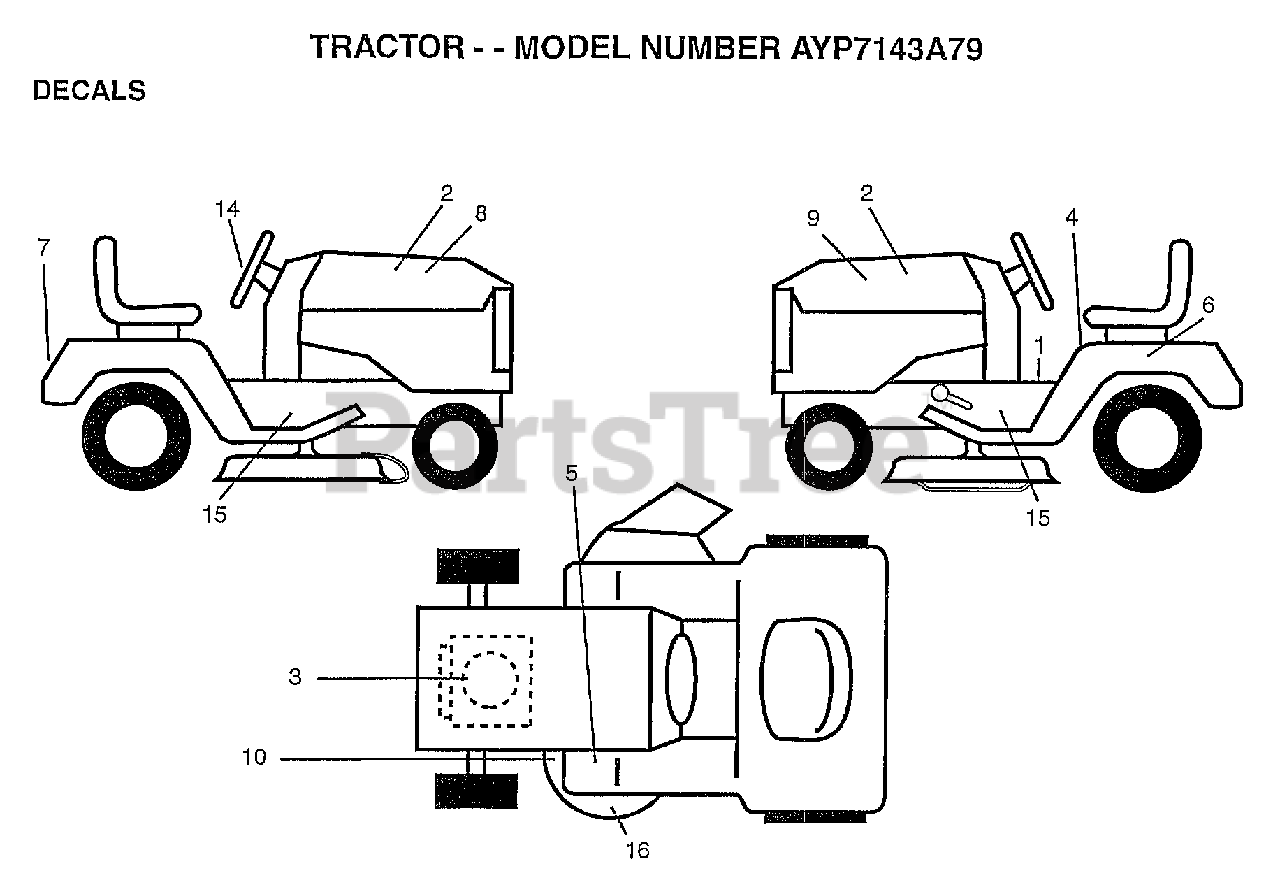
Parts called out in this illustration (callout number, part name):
1	"DECAL DASH,OPER."
2	DECAL.INS.HD.14.5
3	DECAL, ENGINE
4	"DECAL DANGER,FEND"
6	DECAL.BATRY.3-3908
8	DECAL.HD.RH.WIZAR
9	DECAL.HD.LH.WIZAR
10	DECAL
14	DECAL.INS.STRG.WL
15	DECAL CHASSIS WIZ
16	DECAL DECK WIZ +
